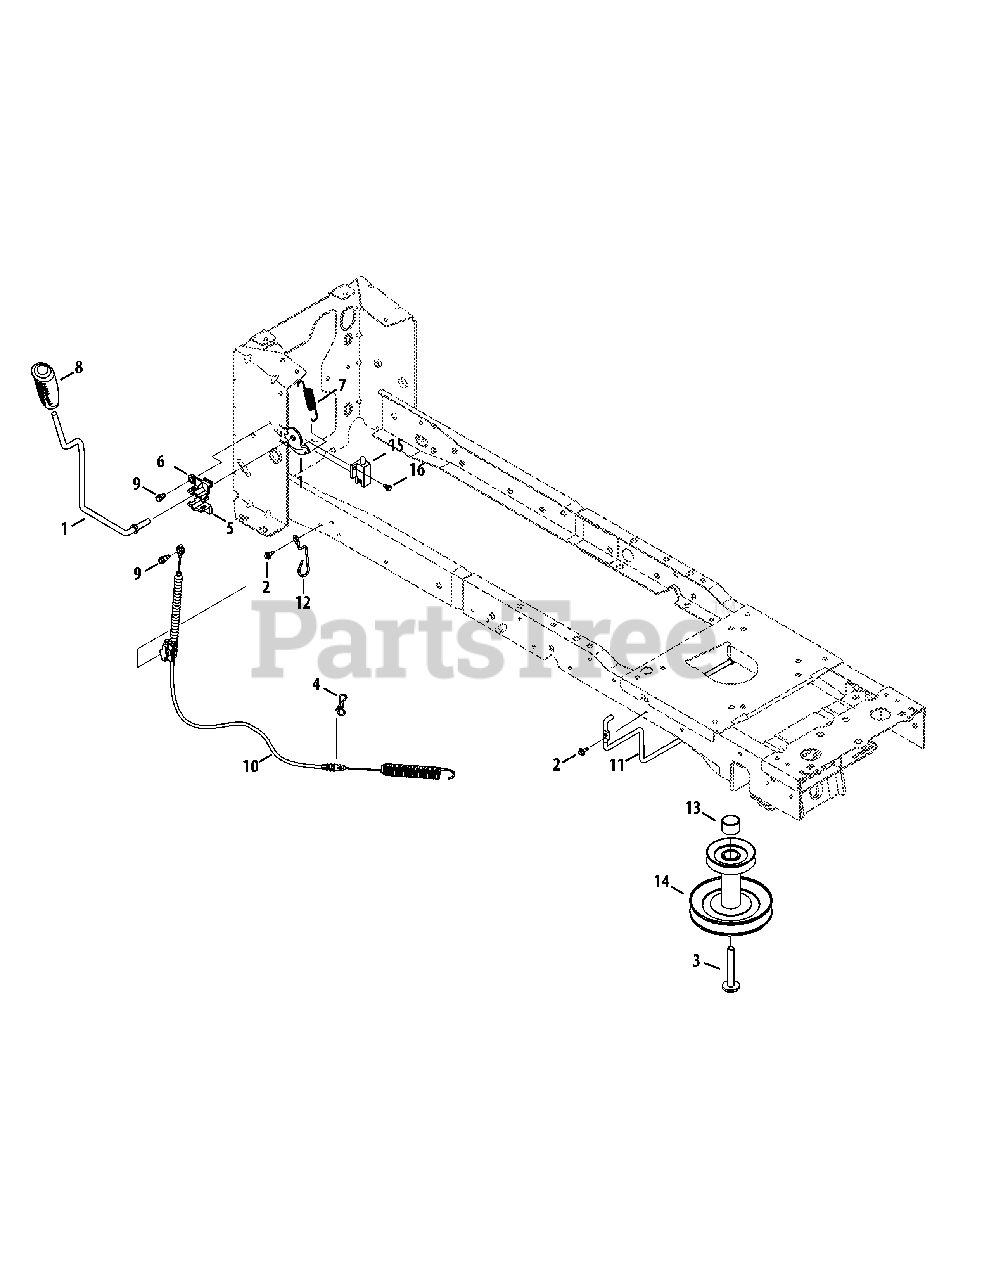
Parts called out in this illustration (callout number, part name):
1	PTO Handle Assembly
2	Screw, M6-1 x .625
3	Hex Cap Screw, 7/16-20 x 3.50
4	Bow-Tie Cotter Pin
5	PTO Handle Mount, RH
6	PTO Handle Mount, Top
7	Extension Spring, .56 OD x 4.52 LG
9	Shoulder Screw, .342 x .335, 1/4-28
10	PTO Cable
11	Engine Pulley Keeper Rod
12	Cable Guide
13	Spacer, Engine Pulley
14	Pulley, Engine, 3.56 x 6.12 Dia.
15	Switch, Interlock
16	Shoulder Screw, #10-32 x .500
